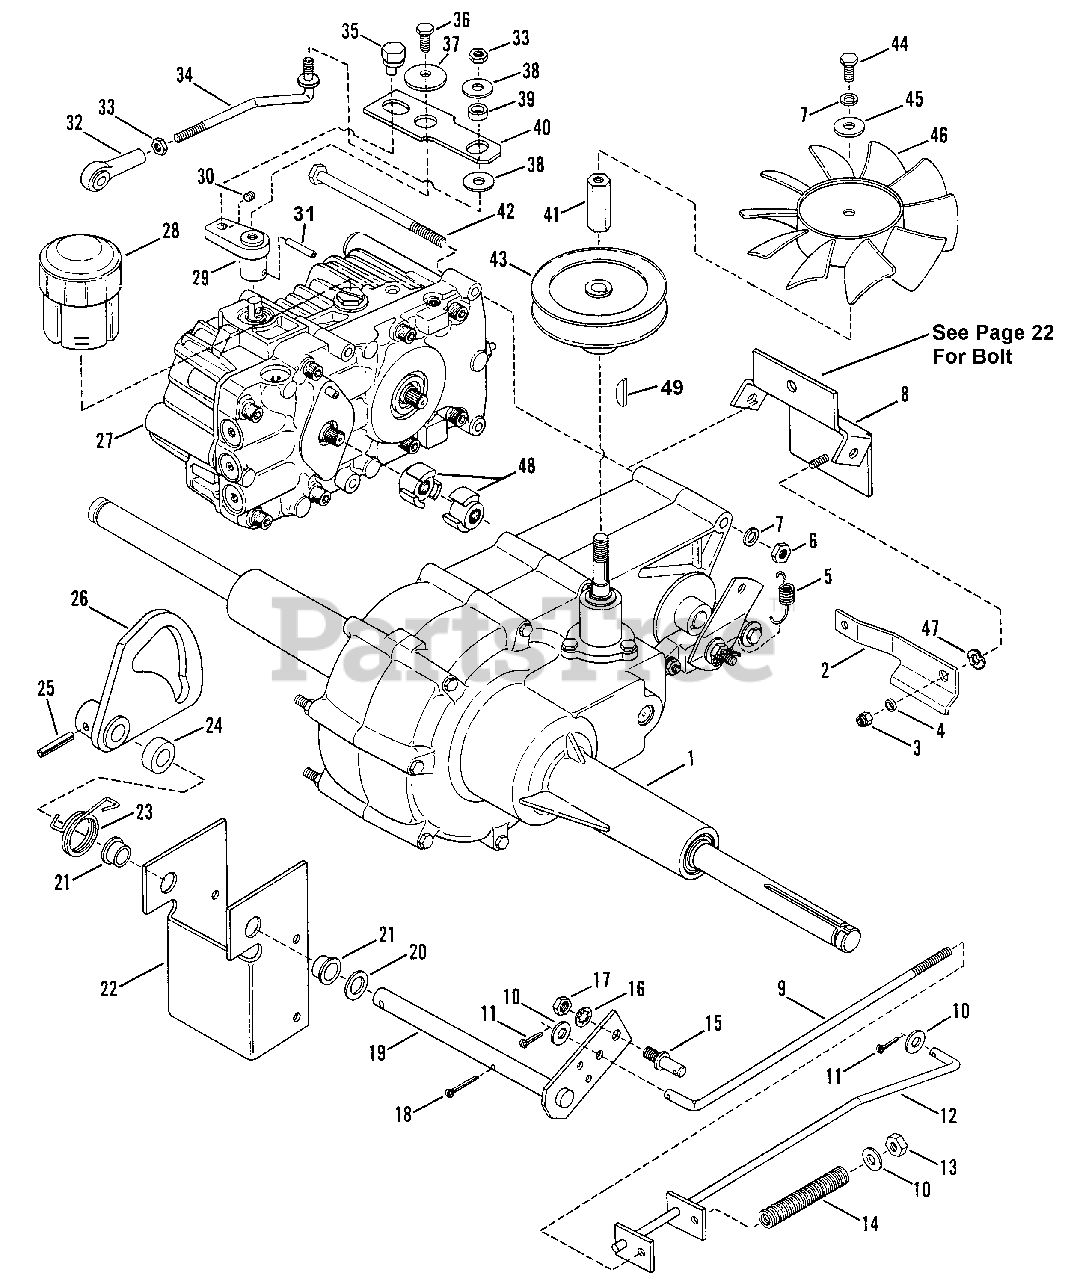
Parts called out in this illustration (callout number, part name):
1	TRANSAXLE ASSEMBLY (HG, 215-1000)
2	LEVER, Release
3	NUT, 1/4-20 Hex Lock
4	SPACER .37 OD x .271 ID x .120 L
5	SPRING, Brake Return
6	NUT, 5/16-18 Hex
7	WASHER, 5/16 Split Lock
8	ASSEMBLY, Torque Bracket
9	ROD, Brake Spring
10	WASHER 5/16 x 7/8 x .083
11	PIN, 5/32 x 1" Cotter
12	ROD, Brake Stop
13	NUT, 5/16-18 Hex Center Lock
14	SPRING, Brake
15	STUD, Neutral Pivot
16	WASHER, 3/8 Internal Tooth Lock
17	NUT, 3/8-24 Hex
18	PIN, 1/8 x 1 1/4" Cotter
19	ASSEMBLY, Neutral Pivot
20	WASHER, .632 ID x 1.0 OD (No longer available, try using 7072801)
21	BEARING, 5/8 Flanged Nylon .625 ID x .719 x .325 (No longer available)
22	SUPPORT, Neutral Pivot
23	SPRING, Torsion
24	SPACER, 1.120 OD x .635 ID x .38 L (No longer available)
25	PIN, 1/4 x 1 1/4" Roll
26	CAM, Neutral Return
27	TRANSMISSION, Hydro (HG BDU-105-120)
28	RESERVOIR ASSEMBLY (HG 2003081)
29	HUB, Speed Control
30	SCREW, 1/4-28, 1/8 Hex Socket Set (No longer available, try using 7077667)
31	PIN, Spiral 5 MM x 36 MM
32	BALL JOINT, 5/16-24
33	NUT, 5/16-24 Hex
34	ROD, Adjustment 4.41" l, 5/16-24 Ends (No longer available)
35	PIN, Eccentric
36	SCREW, 5/16-18 x 1/2" Hex Head Cap
37	WASHER, Cone .32 x 1.4 x .1
38	WASHER, Flat .327 x .875 x .09
39	ROLLER
40	PLATE, Speed Control
41	NUT, Special 3/4 Hex Stock/5/16-24 Thru/9/16-18x1.0 Deep (No longer available)
42	SCREW, 5/16-18 x 4 1/2" Hex Head Cap
43	PULLEY, Drive
44	SCREW, 5/16-24 x 1/2" Hex Head Cap
45	WASHER, Fender 5/16
46	FAN, 7" DIA 10 Blade
47	WASHER, 3/8 Wave
48	COUPLING, Pump
49	KEY, 3/32" x 5/8"
